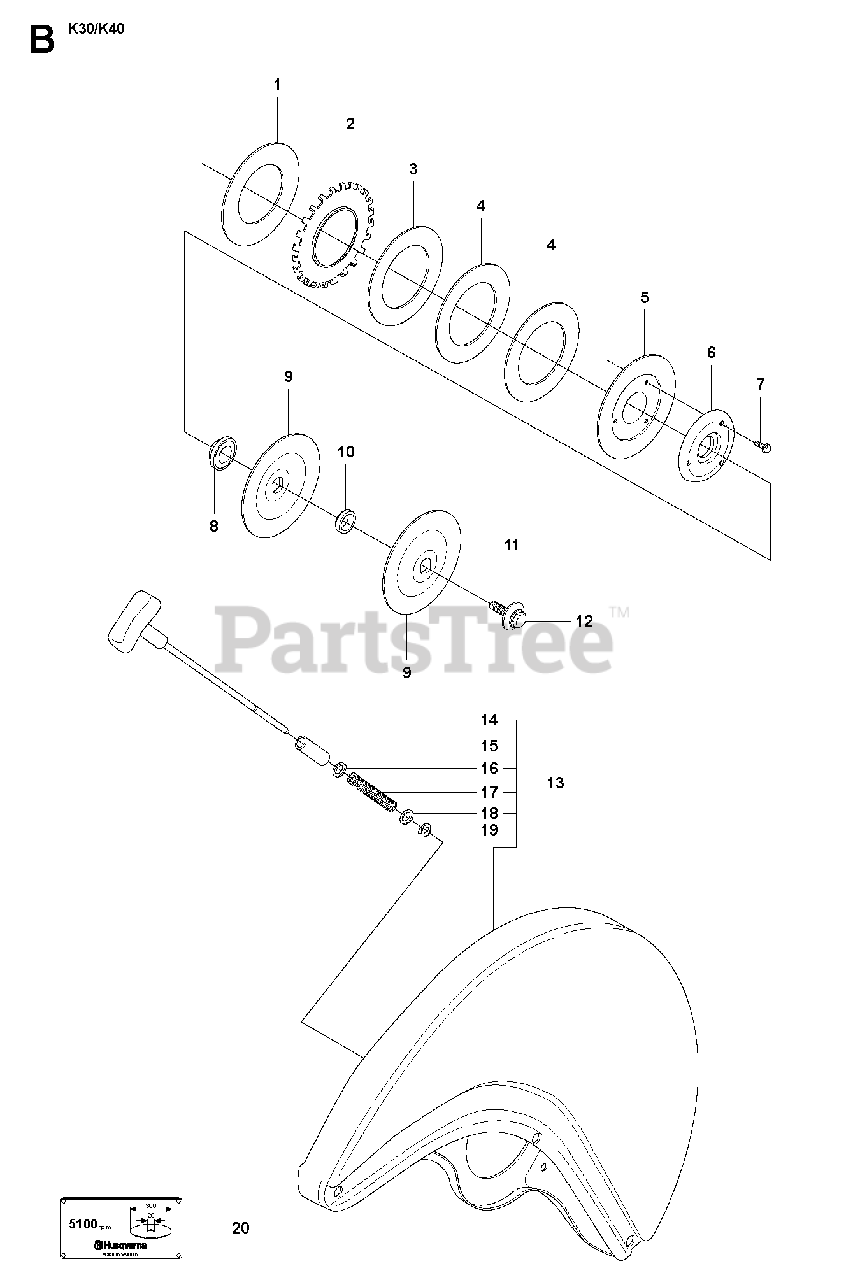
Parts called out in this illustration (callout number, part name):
5	SPRING WASHER
8	SUPPORT FLANGE
9	FLANGE WASHER
10	BUSHINGDiam 30,5mm
10	KITDiam 20mm
10	KITDiam 22,2mm
10	KITDiam 25mm
13	WHEEL GUARDIncl. 14 - 19
